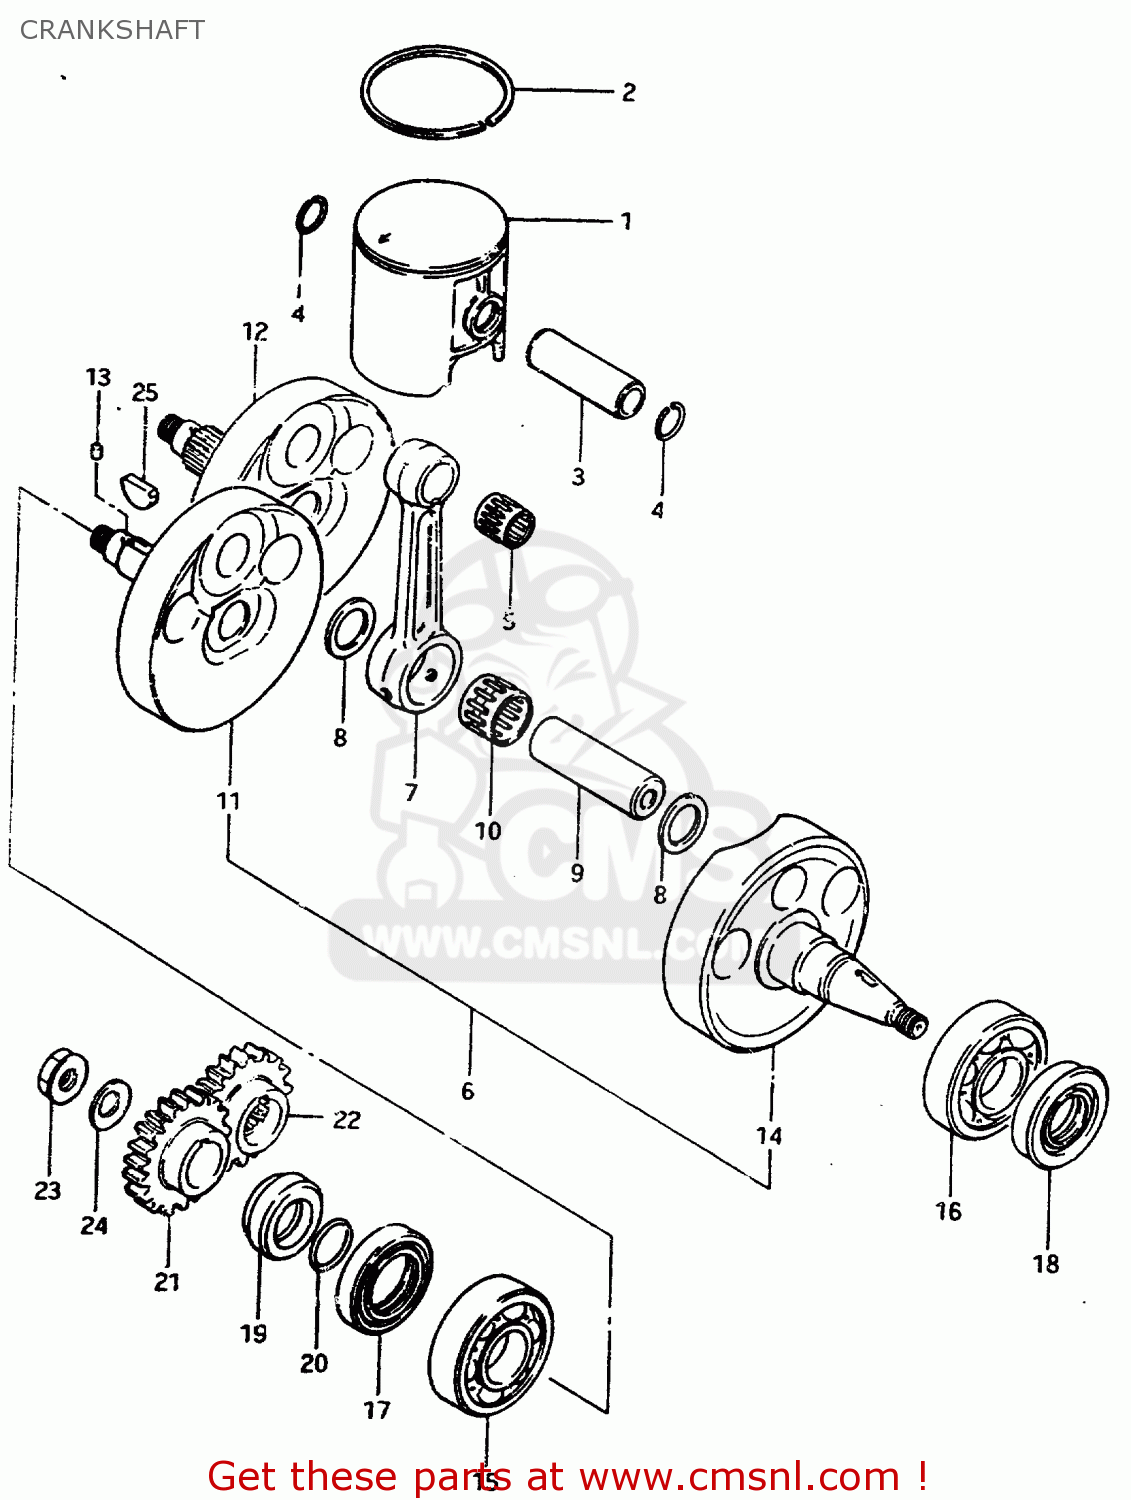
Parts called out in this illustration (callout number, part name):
1	PISTON (70.00MM)
2	RING,PISTON
3	PIN,PISTON (18MM)
4	CIRCLIP,PISTON PIN
5	BEARING(18X23X22)
6	CRANKSHAFT ASSEMBLY
7	ROD,CONNECTING
8	WASHER(24X29X1.5)
9	PIN,CRANK
10	BEARING
11	CRANKSHAFT,RIGHT
12	CRANKSHAFT
13	PIN 3X5
14	CRANKSHAFT,LEFT
15	BEARING(25X62X17)
16	BALL BEARING 30X62X16
17	SEAL,OIL(36X52X8)
18	SEAL,OIL(19.6X37X8)
19	SPACER,PRIMARY DRIVE GEAR
20	O RING(D:2.4,ID:21.8)
21	GEAR,PRIMARY DRIVE
22	GEAR,PRIMARY DRIVE (NT:
23	NUT
24	WASHER
25	KEY
26	PISTON SET
